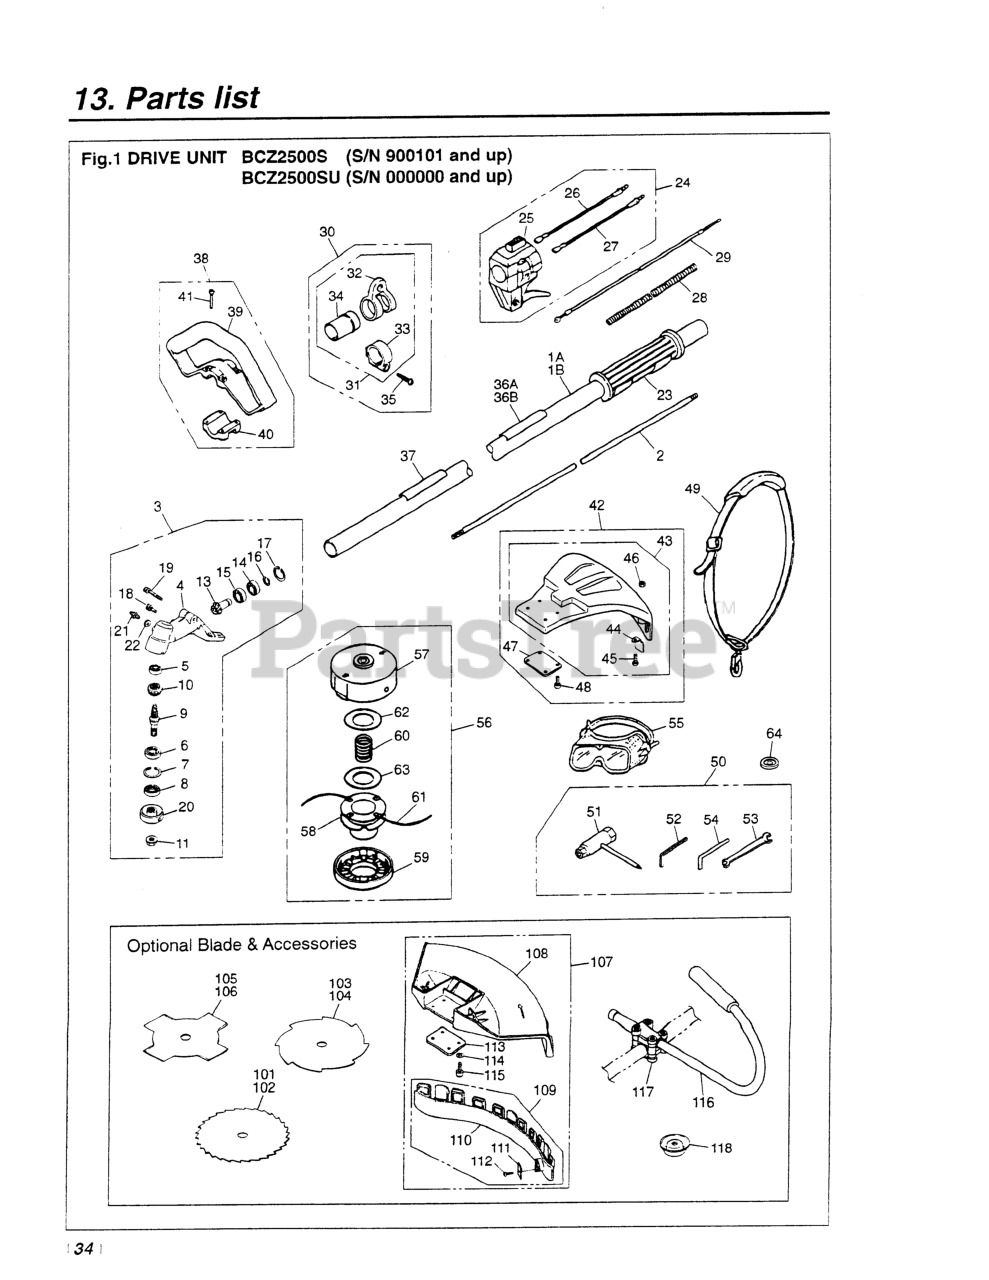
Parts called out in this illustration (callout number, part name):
1B	PIPE COMPLETE
3	GEARCASE ASSY (RPLS -13000)
4	GEARCASE
5	BEARING (RPLS T3300-13521)
6	BEARING (RPLS T3403-13510)
7	RING, SNAP, M26 X 1.2
8	SEAL, OIL
9	SHAFT
10	GEAR
11	NUT
13	PINION
14	BEARING (RPLS T3300-13531)
15	BEARING (RPLS T3403-13530)
16	RING, SNAP (RPLS T3300-13330)
17	RING, SNAP, M24 x 1.2
18	BOLT, M5 X 10
19	BOLT
20	HOLDER (A)
21	FITTING, GREASE
22	WASHER, M6 X .8
23	GRIP (RPLS 3577-32140 & 3220-
26	CORD (A), BLACK
27	CORD (B), RED
28	TUBE (RPLS 4900-72141)
29	CABLE (RPLS 5580-83100)
30	HANGER ASSEMBLY
31	HANGER COMPLETE
32	HANGER
33	CLAMP
34	SLEEVE
36A	PLATE, NAME (BCZ2500S)
36B	PLATE, NAME
37	PLATE, CAUTION
38	HANDLE ASSEMBLY
39	HANDLE
42	GUARD ASSY (RPLS -24000)
43	GUARD COMP (RPLS. -24100)
44	BLADE (RPLS T3002-24120)
46	NUT
47	PLATE
48	BOLT (USE 3310-31720)
51	SOCKET
52	WRENCH (TOOL)
53	SPANNER, 8 X 10 (RPLS 2540- )
54	BAR
55	GOGGLE
56	4
57	CASE (RPLS -15112)
58	HOLDER, CORD (RPLS -15141)
59	COVER (RPLS -15130)
60	SPRING (RPLS -99161)
61	CORD
62	PLATE, LARGE
63	PLATE, SMALL
64	HOLDER (B)
101	BLADE, 9
102	BLADE, 9
103	BLADE, 8
104	BLADE, 9
105	BLADE, 8
106	BLADE, 9
107	GUARD ASSEMBLY
108	GUARD
109	PLATE COMPLETE
110	PLATE
111	BLADE
113	PLATE
114	WASHER, SPRING M4 x 1.3
115	BOLT, M5 X 16
116	HANDLE, J
117	BRACKET ASSY (REPLACES -14100)
118	COVER
